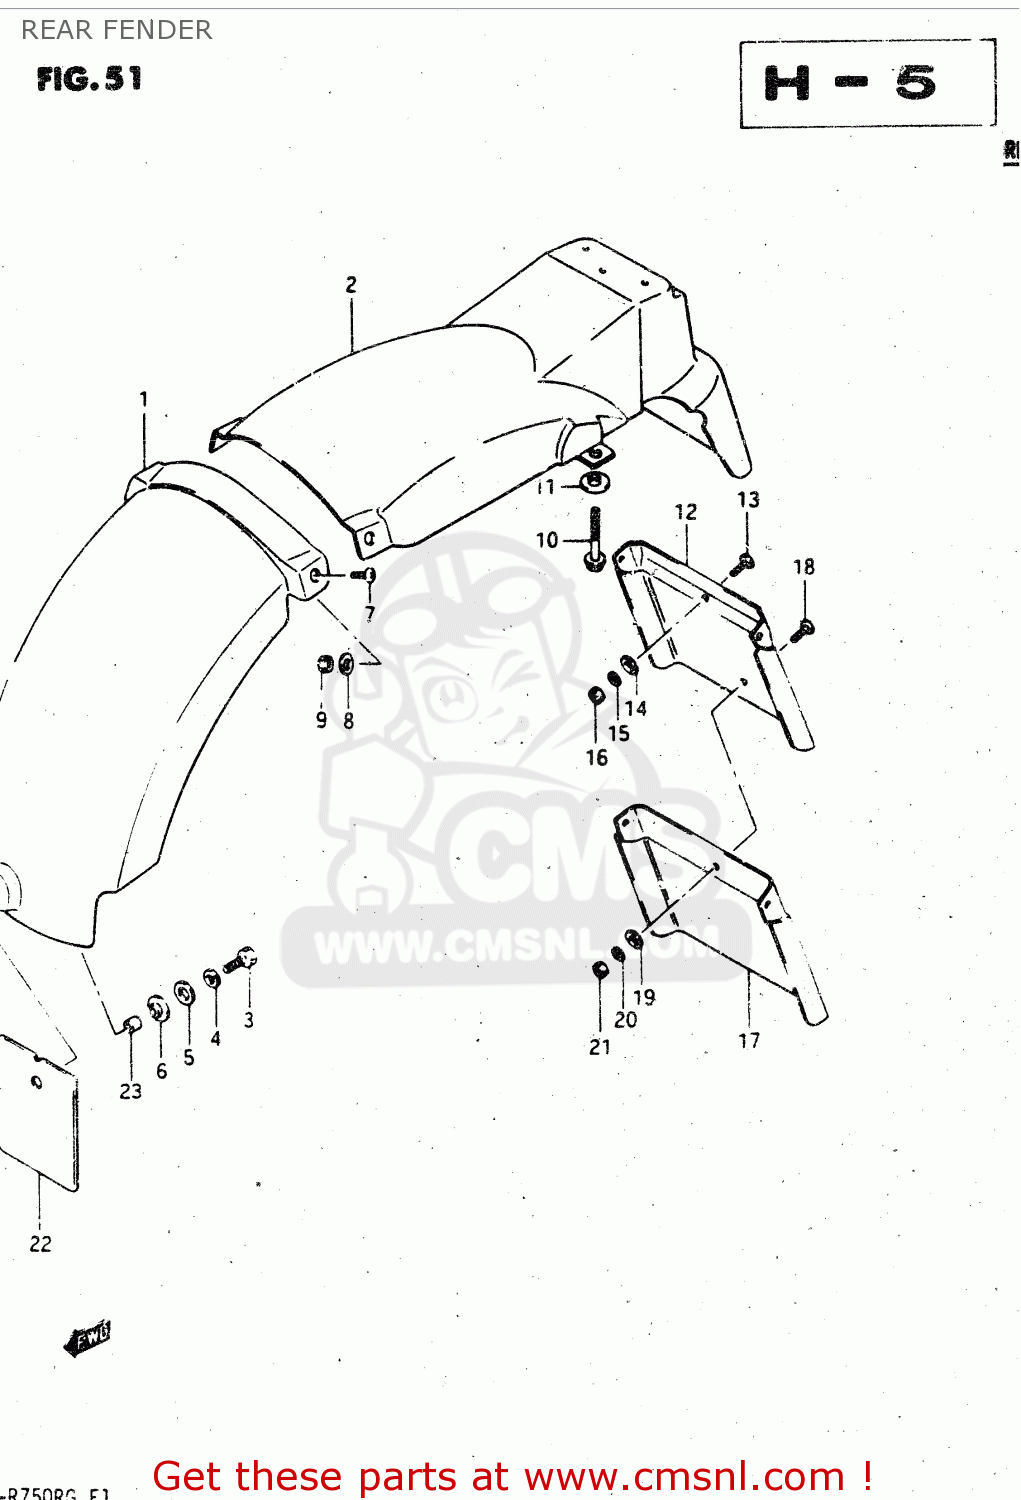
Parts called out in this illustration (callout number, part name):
1	FENDER,REAR
2	FENDER,REAR
3	BOLT 6X30
4	WASHER,LOCK
5	WASHER
6	WASHER
7	SCREW
8	WASHER
9	NUT 6MM
10	BOLT
11	WASHER
12	EXTENSION
13	SCREW 6X12
14	WASHER
15	WASHER,LOCK
16	NUT
17	MUD GUARD
18	SCREW
19	WASHER(6.5X16X1.2)
20	WASHER,LOCK
21	NUT
22	MUD GUARD,REAR FENDER,FRONT
23	SPACER (6.8X10X10)
